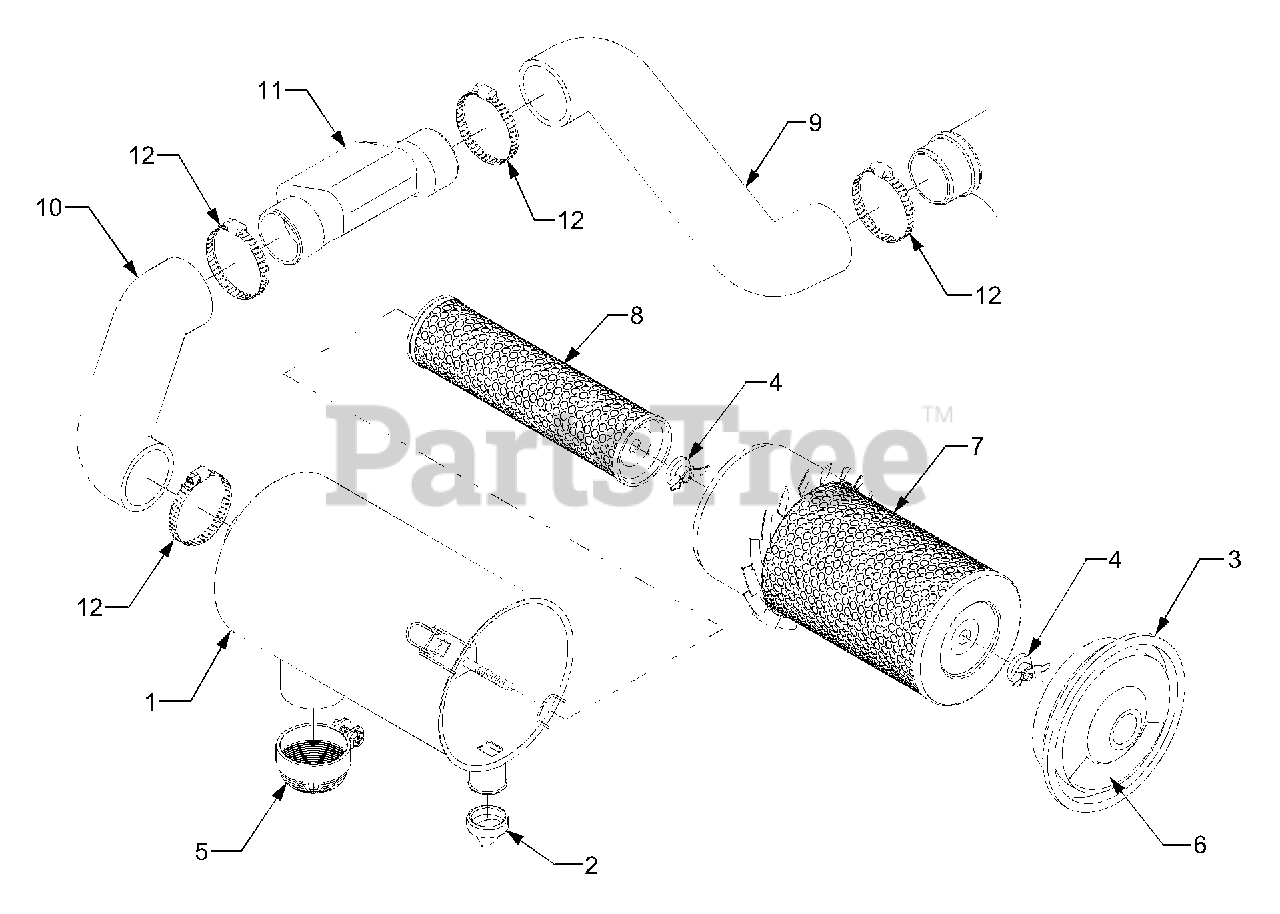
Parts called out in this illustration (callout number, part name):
1	Body, Aircleaner
3	Cover, Aircleaner
7	Element 1, Aircleaner
8	Element 2, Aircleaner
9	Pipe 1, Inlet
10	Pipe 2, Inlet
11	Pipe 3, Inlet
